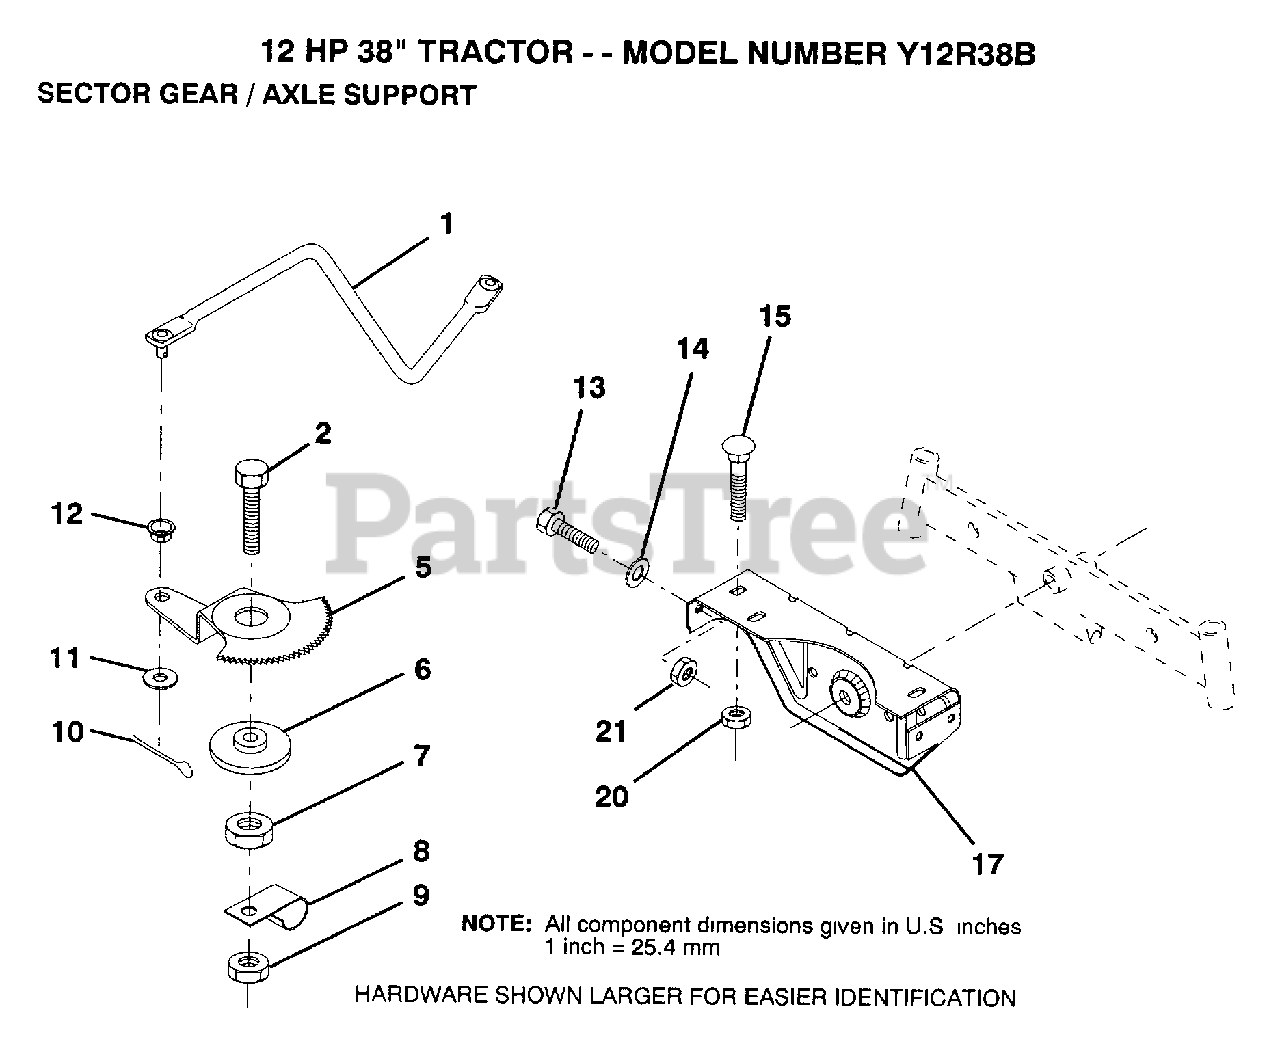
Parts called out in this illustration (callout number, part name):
1	DRAG LINK
2	"BOLT,HEX"
5	GEAR SECTOR
6	BUSHING
7	NUT
8	CLIP INSULATOR
9	NUT LTV
10	COTTER PIN
11	WASHER
12	BUSHING.DRAGLINK
13	BOLT
14	WASHER
15	BOLT
17	SUPT AXLE FRONT
